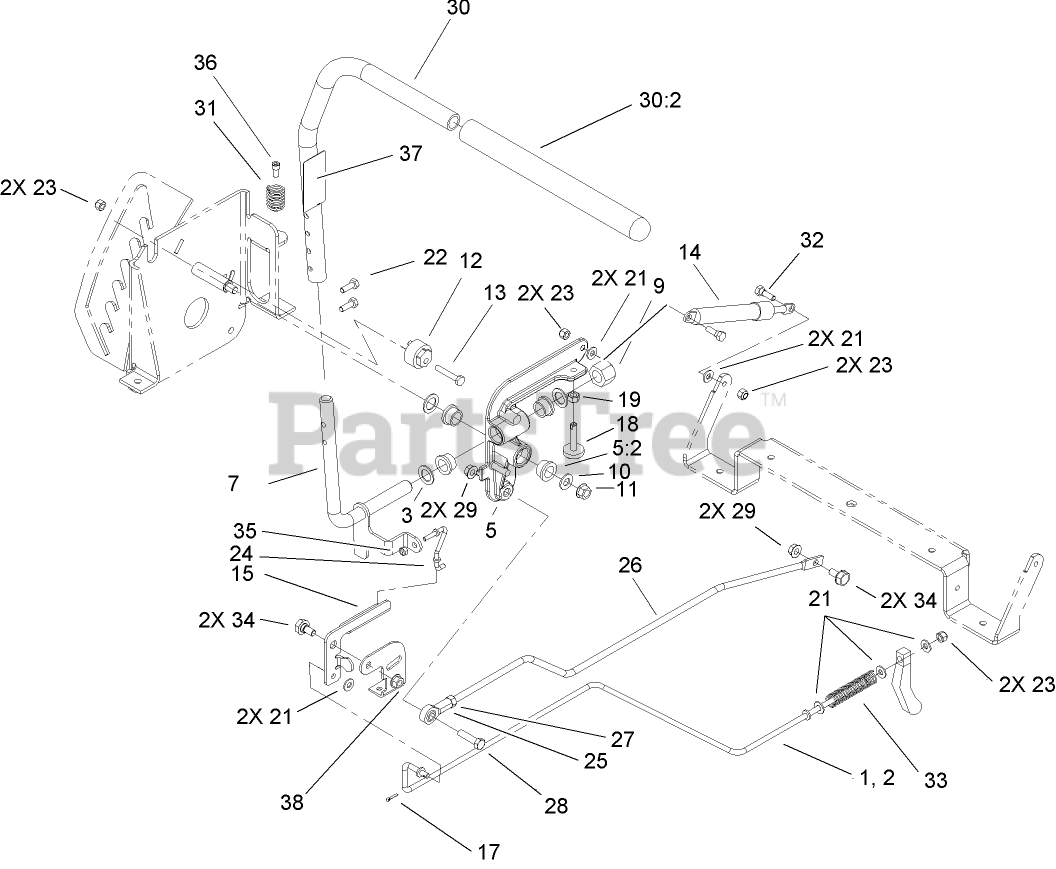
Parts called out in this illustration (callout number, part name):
1	ROD-BRAKE, LH
2	ROD-BRAKE, RH
3	WASHER-THRUST
5	RH ACTUATOR ARM W/BUSHING ASM
5:2	BUSHING
7	LH PIVOT SHAFT ASM
9	NUT-LOCK, NI
10	WASHER-FLAT
13	SCREW-HH
15	BELLCRANK
17	PIN-COTTER
18	STOP-ADJUSTMENT
19	NUT-HEX
21	WASHER-FLAT
22	SCREW-HH
23	NUT-LOCK, NI
24	LINK-BRAKE
25	BALLJOINT-RH
26	ROD-HYDRO
27	NUT-HEX
28	SCREW-HH
29	NUT-HF
30	HANDLE ASM
30:2	GRIP-CONTROL, MOTION
31	SPRING-COMPRESSION
32	BOLT-SHOULDER
33	SPRING-COMPRESSION
34	BOLT-SHOULDER,HFH
35	NUT-LOCK, NI
36	SCREW-HSH
38	NUT-HF
